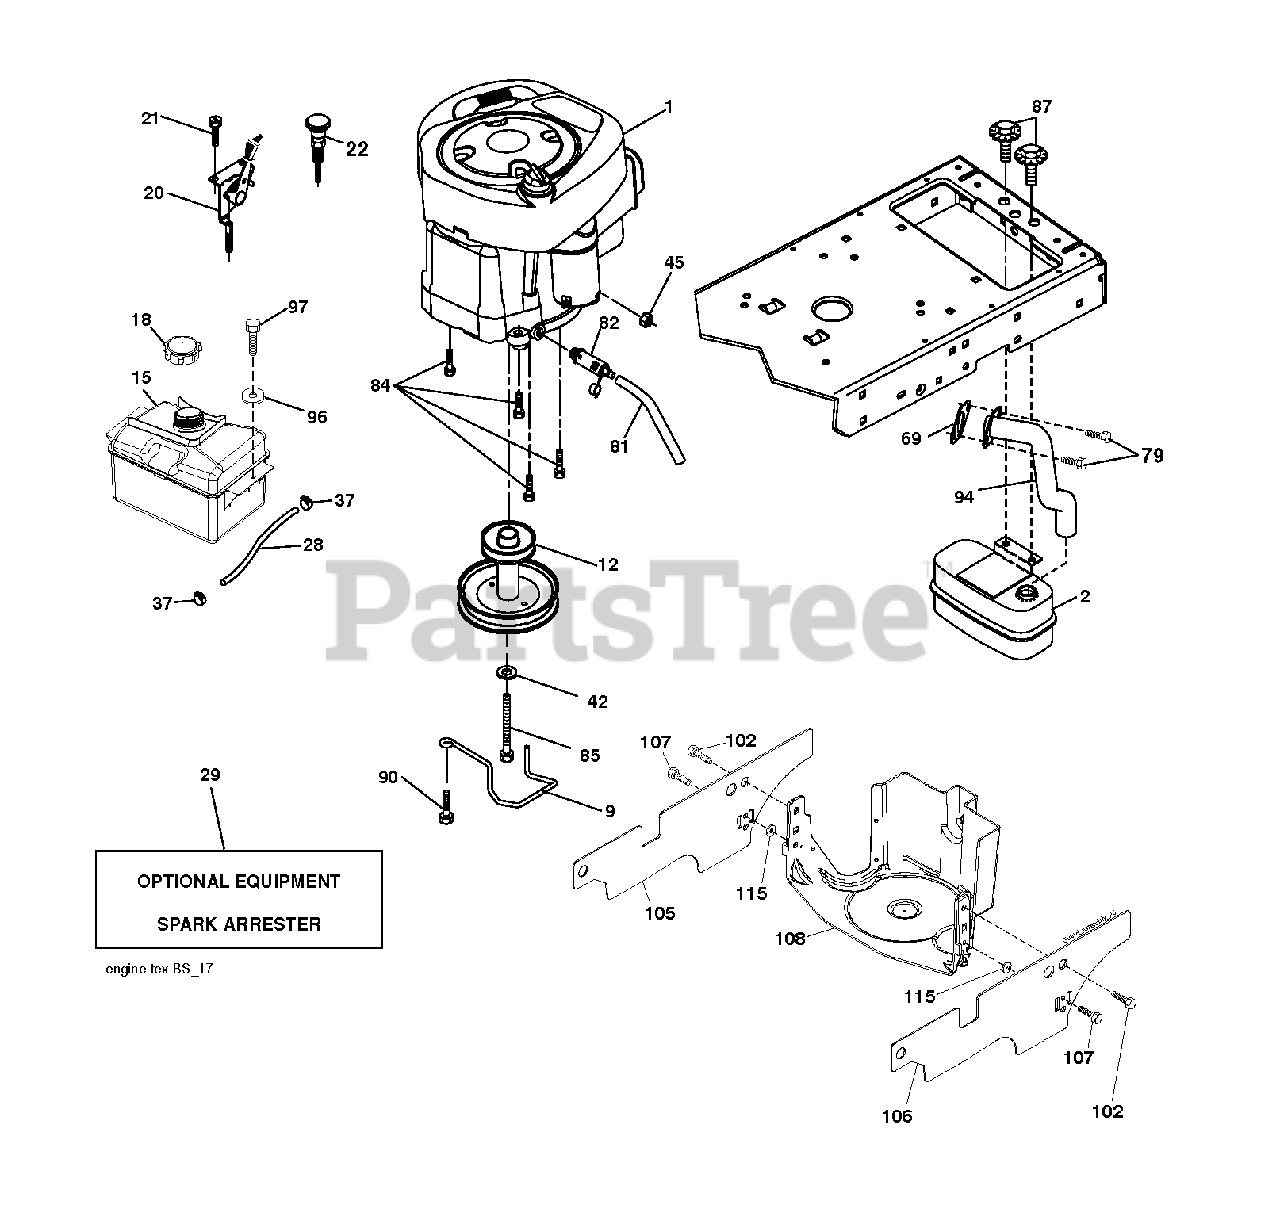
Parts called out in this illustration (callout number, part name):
2	MUFFLER.SINGLE.CYL.KOHL/B&S
9	KEEPER.BELT.ENGINE.3.25
12	PULLEY ENGINE
15	TANK FUEL FRT 1.5 GAL
18	FUEL CAP
20	CONTROL.TH/CK.C.
21	SCREW.#10 X 0.750.BOS THREAD
28	LINE.FUEL.20
29	ARRESTER SPARK (OPTIONAL)
37	HOSE CLAMP
42	LOCKWASHER
45	NUT
69	REPL BY 532 27 22-93
79	SCREW.SOCKET HD.5/16-1
81	TUBE, DRAIN OIL ASM.
82	PLUG DRAIN OIL EASY
84	SCREW.3/8-16
85	BOLT HEX 7/16-20X4-1/4"
87	BOLT, 5/16-18 X 1 3/4
90	SCREW 3/8-16X1
94	EXHAUST.TUBE.B&S.
97	SCREW HEXWSHR 1/4-20X3/4
102	SCREW
107	SCREW.1/4-20X5/8
115	PALNUT 1/4
